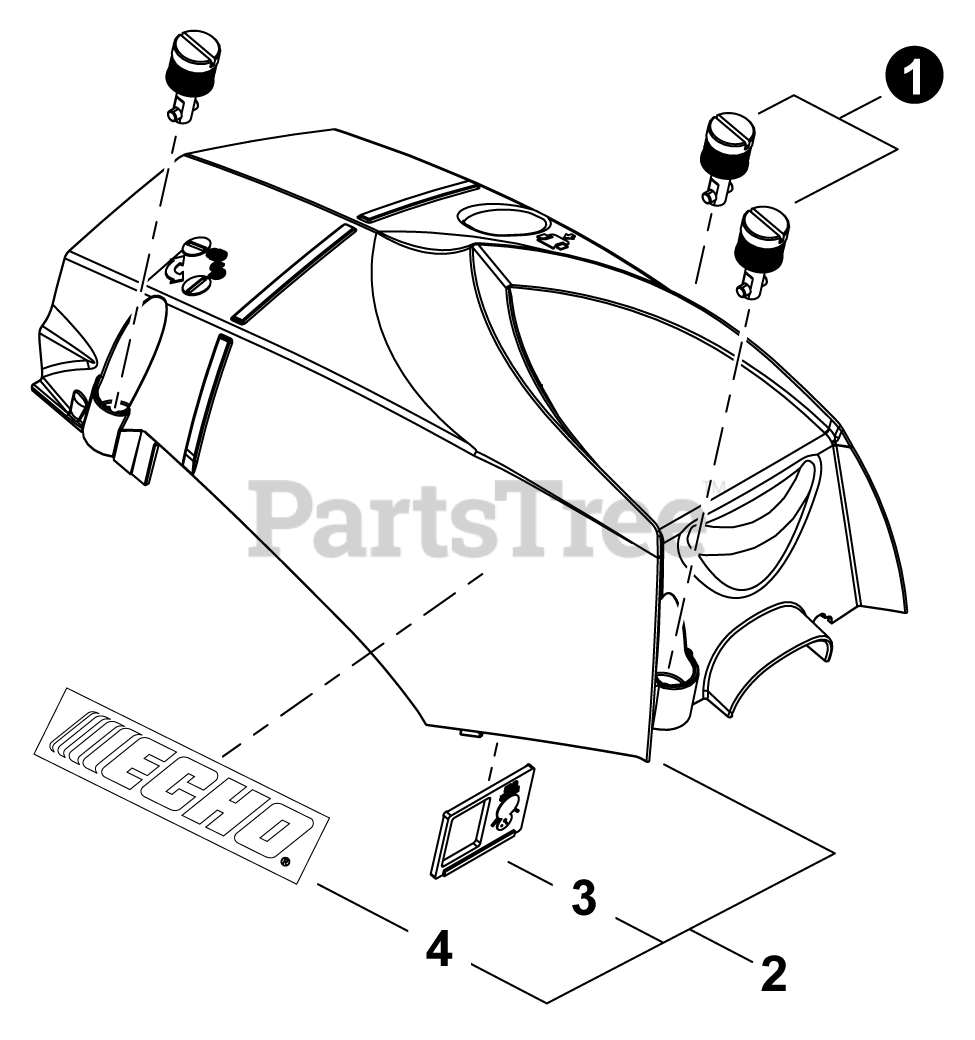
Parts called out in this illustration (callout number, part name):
1	PIN, SNAP
2	COVER ASSY, ENGINE
3	PLATE, SHUTTER
4	LABEL - ECHO
